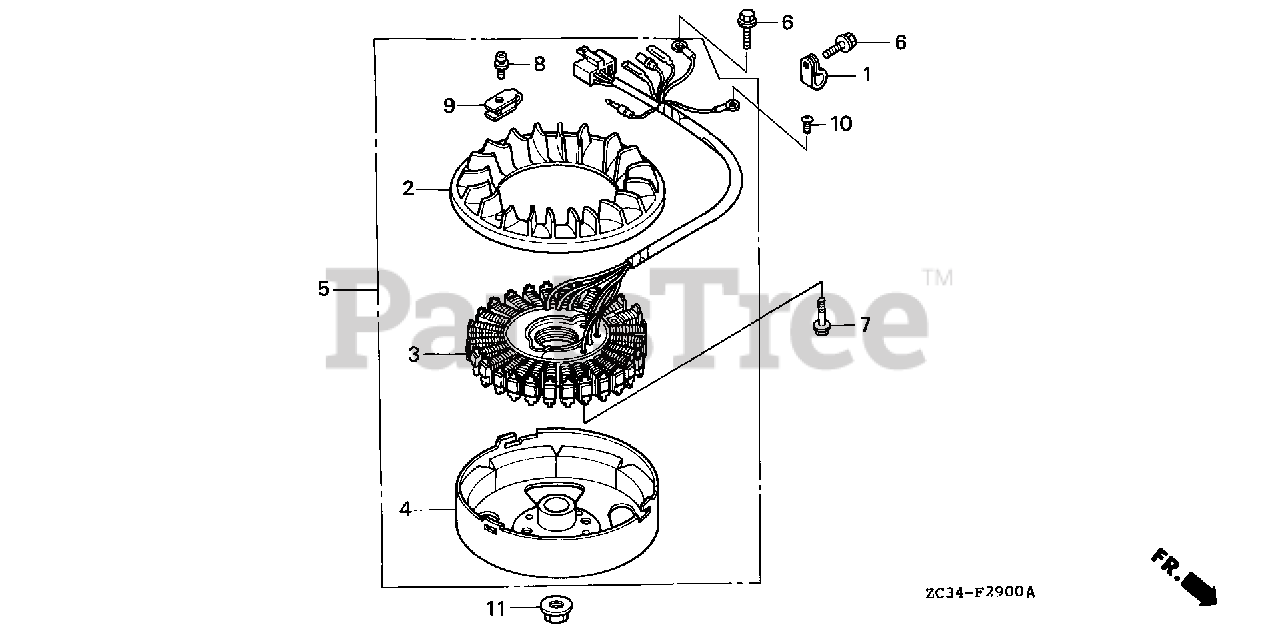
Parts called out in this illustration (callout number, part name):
1	CLAMP, IGNITION WIRE
2	FAN, COOLING
3	STATOR ASSY. (EM-A)
5	GENERATOR ASSY. (EM-A)
6	BOLT, FLANGE (5X10)
7	BOLT, FLANGE (5X20)
8	SCREW, PAN (4X12)
9	CLIP, GENERATOR FAN
10	SCREW, PAN (5X8)
11	NUT, FLANGE (10MM)
